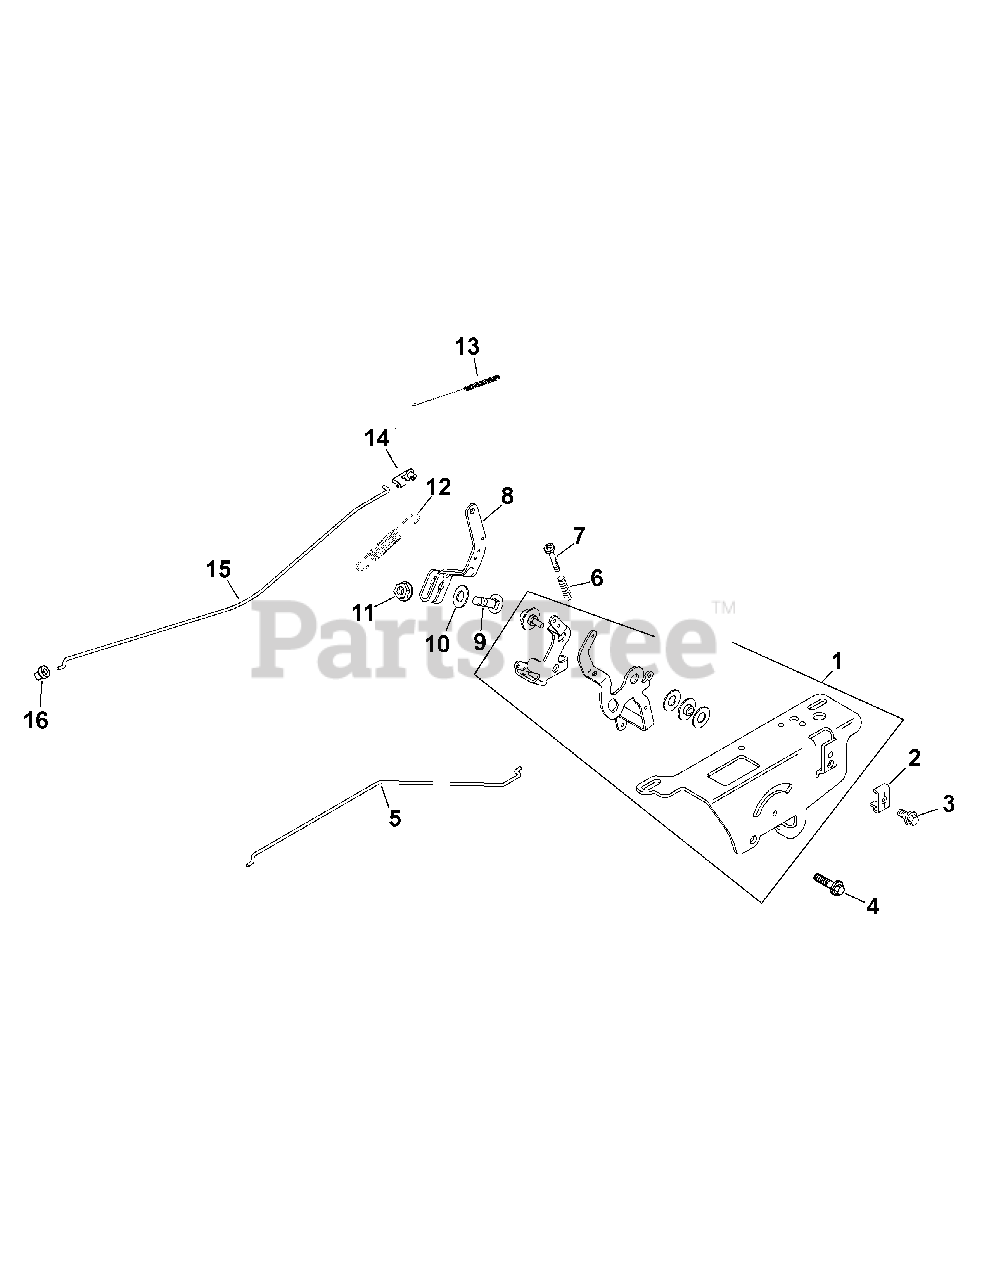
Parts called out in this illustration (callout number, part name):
1	Speed Control Assembly (Inc. 4, 6,7 & 12)
2	Cable Clamp
3	Hex Flange Screw, M5 x 0.8 x 16
4	Socket Screw, M6 x 1.0 x 20
5	Single Wire Choke Linkage
6	Speed Control Spring
7	Screw, M4 x 0.7 x 25
8	Governor Lever
9	Bolt, 1.4-20 x 1
10	Lock Washer, 1.4
11	Hex Flange Nut, 1.4-20
12	Governor Spring
13	Linkage Spring
14	Throttle Linkage Bushing
15	Throttle Linkage
16	Linkage Retaining Bushing
